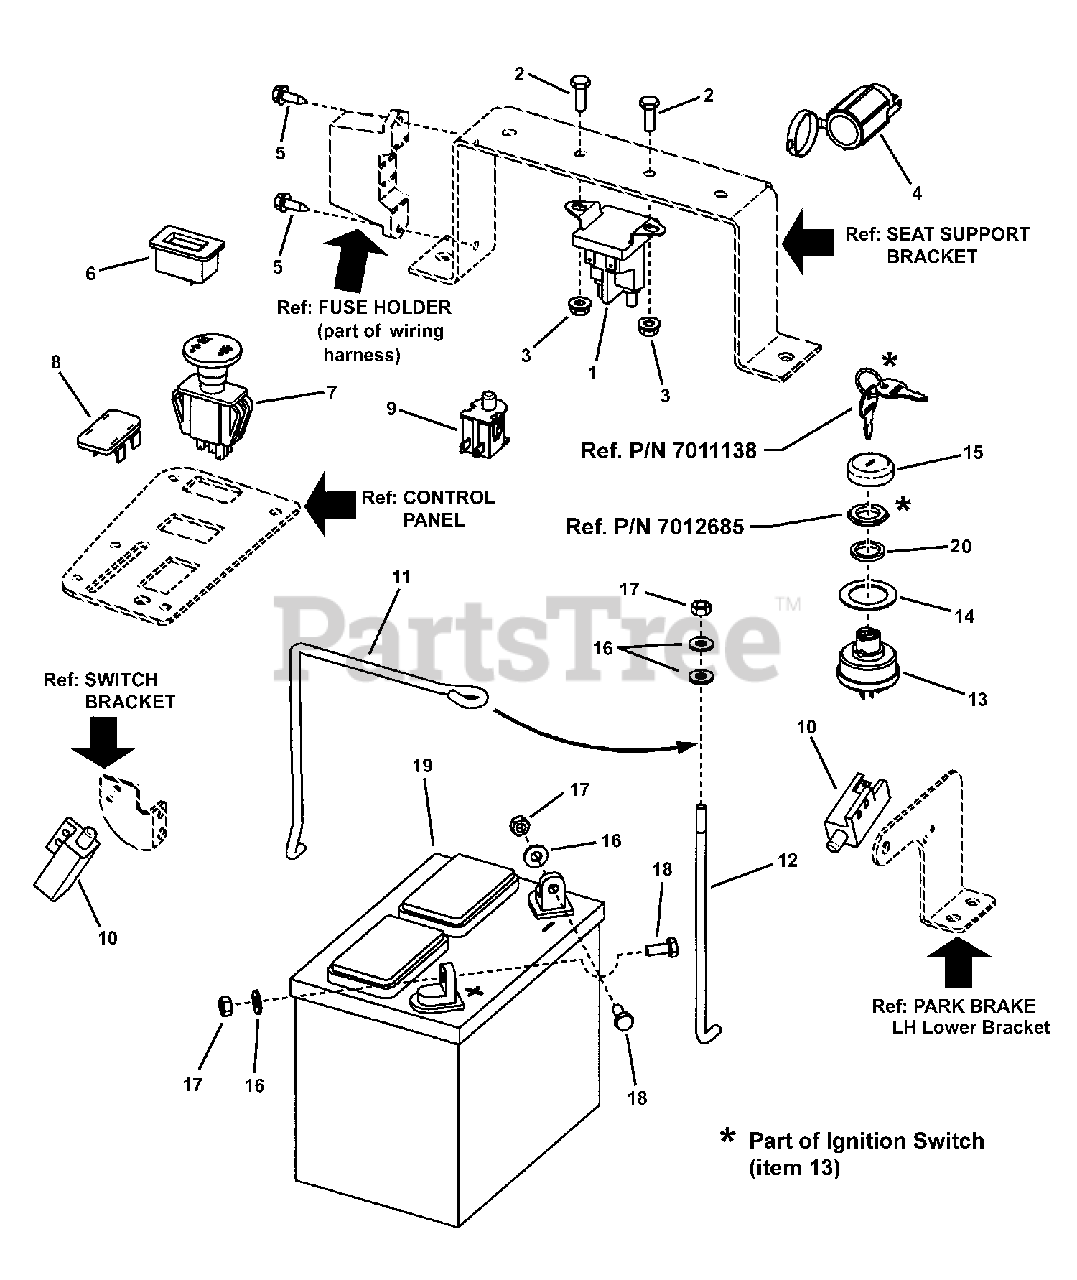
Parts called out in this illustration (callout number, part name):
1	SOLENOID - Super Trombetta- 2 Terminal
2	SCREW, 1/4-20 x 1" Hex Head Cap, GR 5
3	NUT, 1/4-20 Hex Flange Lock, GR 5
4	12 VOLT DC POWER OUTLET
5	SCREW, 1/4-20 x 3/4" Hex Washer Self-Tap
6	HOUR METER, Inductive
7	SWITCH, PTO, Yellow
8	PLUG, Plastic Black
9	SWITCH, Seat (NC)
10	SWITCH- DPDT (NC/NO) (Grey)
11	BATTERY BRACKET
12	BATTERY HOLD DOWN
13	SWITCH, Ignition-Afterfire Solenoid
14	MACHINERY BUSHING
15	BEZEL
16	WASHER, .28 x .63 x .06 Flat, GR 5
17	NUT, 1/4-20 Hex Center Lock, GR 5 or B
18	SCREW, 1/4-20 x 5/8" Hex Head Cap, GR 5
19	BATTERY, 12 VOLT, 230 CCA
20	SPACER, .65 x .88 x .10
